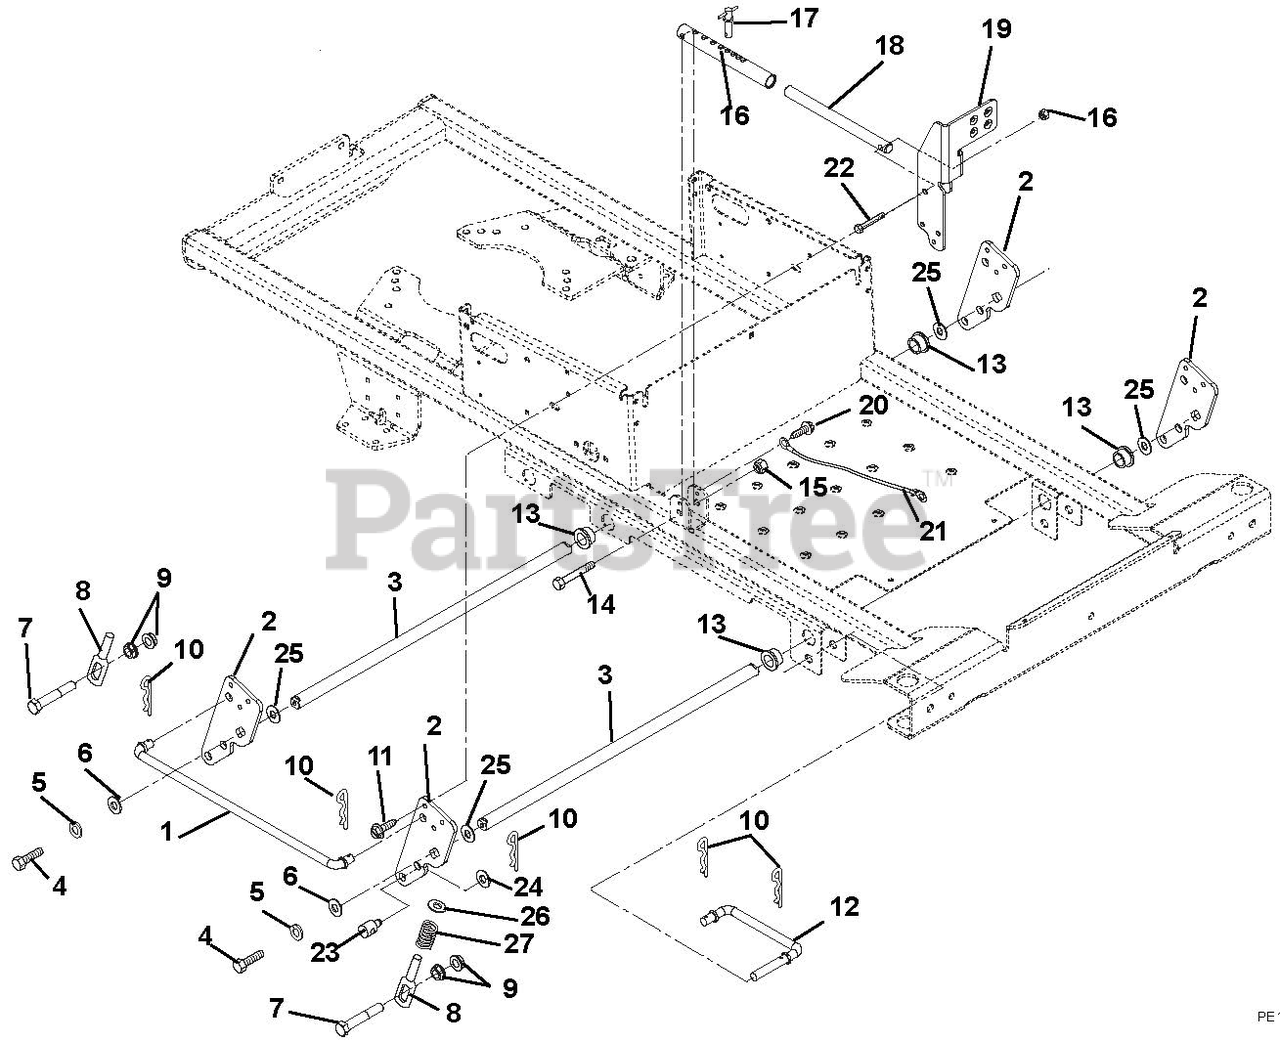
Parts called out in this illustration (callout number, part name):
1	Rod, Lift
2	Lift Arm
3	Shaft, Lift
4	Bolt, Hex .31-18 x 1.00 Grade 5
5	Washer, Flat Steel .328 x .87 x .179
6	Washer, Flat Steel .344 x 1.125 x .135
7	Bolt, Hex .50-13 x 3.00 Grade 5
8	Deck Link
9	Nut, Spin Lock Flange .50-13
10	Pin, Hair #16
11	Screw, Tap .31-18 x .50
12	Link, Drag
13	Bushing, Flange .750 x 1.000 x .625 x 1.250
14	Bolt, Hex .38-16 x 2.00 Grade 5
15	Nut, Flange Nyloc 3/8-16
16	Tube, Lift Stop
17	Pin, Spring Ball .375OD x 1.50
18	Rod, Lift
19	Pedal, Foot Lift
20	Screw, Tap .25-20 x .50
21	Cable, Hood
22	Bolt, Hex .38-16 x 2.50 Grade 5
23	Trunnion
24	Washer Flat Steel .511 x 1.441 x .125
25	Washer Flat Steel .755 x 1.375 x .062
26	Washer Flat Steel .515 x 1.625 x .250
27	Spring, Compression .105 x 1.35 x 2.00
